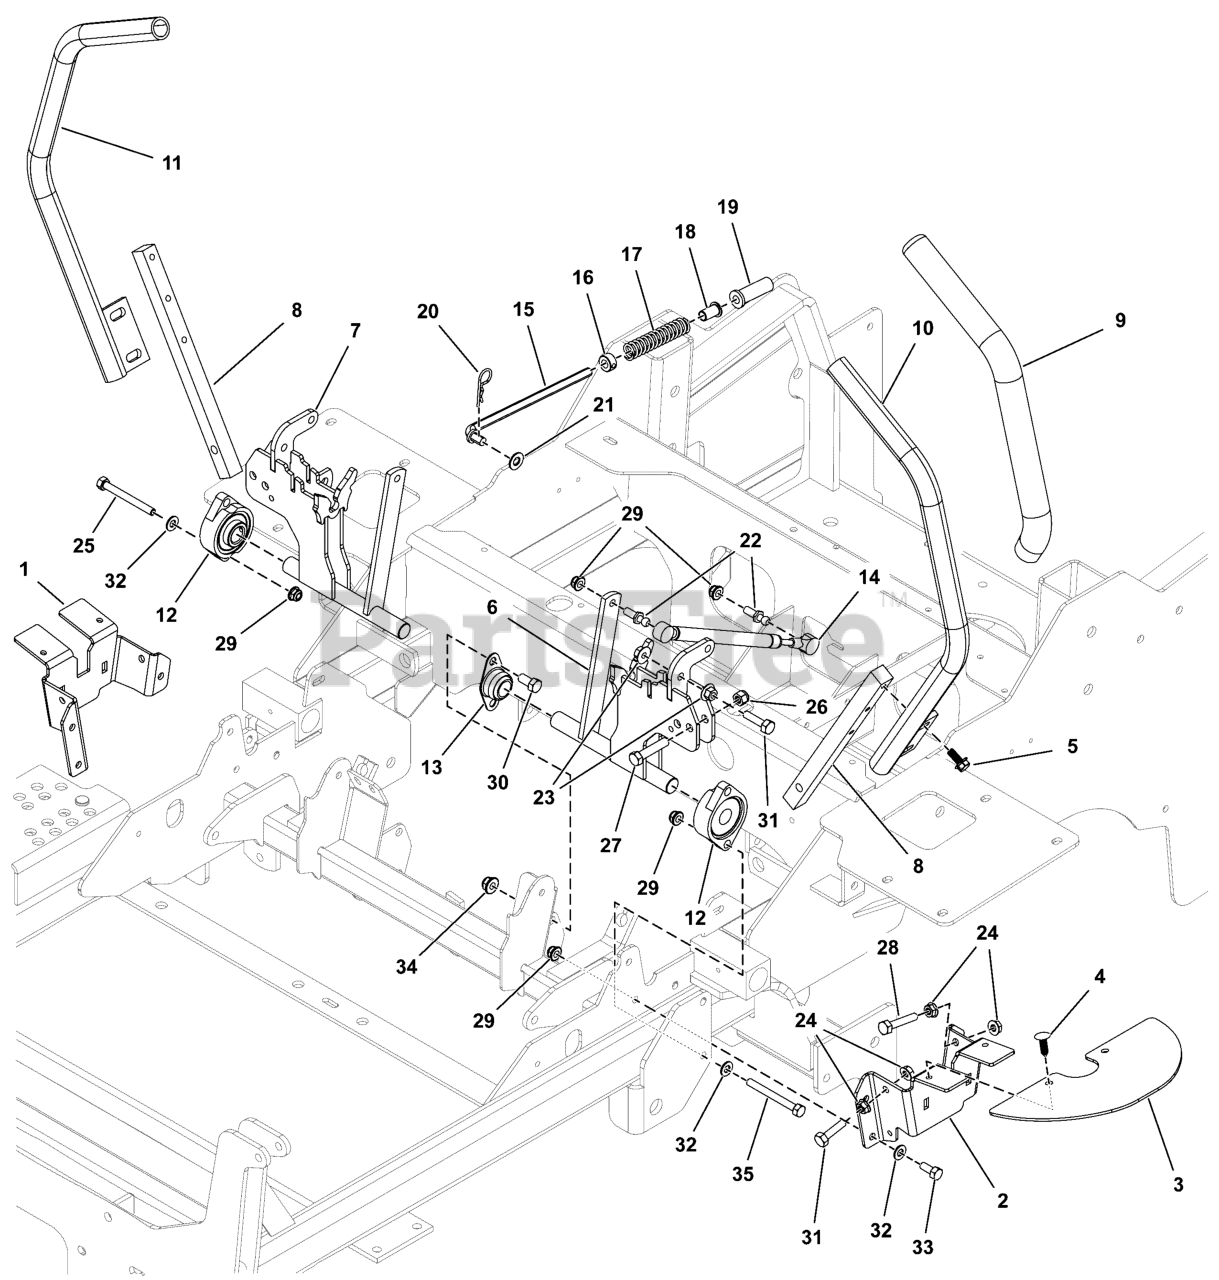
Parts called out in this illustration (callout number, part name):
1	PLATE, Neutral Lock, RH - BLK
2	PLATE, NEUTRAL LOCK, LH - BLK
3	GUARD, RUBBER MOTION CONTROLS
4	PUSH RIVET (TREE TYPE), BLACK
5	SCREW, 5/16-18x0.750, GR5, WHIZ-LOCK, ZC
6	WELD, CONTROL SHAFT, LOCKOUT, LH - BLK
7	WELD, CONTROL SHAFT, LOCKOUT, RH - BLK
8	MOUNT, CONTROL ARM - BLK
9	GRIP, FOAM, 1" ID, 16" LONG
10	WELD, HANDLE MOTION CNTRL, 16.5, 1.0, LH - BLK
11	WELD, HANDLE MOTION CNTRL, 16.5, 1.0, RH - BLK
12	BEARING, FLANGE
13	BEARING, BRONZE FLANGE, 3/4"
14	DAMPENER, CONTROL,#(P6709/P3610)
15	ROD, NEUTRAL RETURN, CZ
16	COLLAR, 3/8" Set
17	SPRING, REVERSE RETURN
18	BUSHING, FLANGE 3/8ID X 7/8 LONG
19	FLANGED BUSHING, 3/8IDX.63ODX.8125FL
20	3/32 X 1-5/8 HAIR PIN CLIP
21	WASHER, 3/8 SAE
22	10MM BALL STUD, 5/16-18 X 3/4 THDS
23	NUT, 5/16-18 HEX SERRATED FLANGE (LARGE)
24	NUT, 5/16-18 HEX SERRATED FLANGE (SMALL)
25	BOLT, 5/16-18 X 3" GD5 YZ
26	NUT, 3/8-16 HEX NYLON LOCK
27	BOLT, 3/8-16 X 1-3/4" GD5 CZ
28	BOLT, 5/16-18 X 1-3/4 TFL, GD5 YZ
29	NUT, 5/16-18 HEX NYLOCK FLANGE NUT
30	BOLT, 3/8-16 X 3/4" GD5 CZ
31	BOLT, 5/16-18 X 1-1/4 GD5 TFL, CZ
32	WASHER, 5/16" SAE
33	BOLT, 5/16-18 X 3/4 GD5
34	NUT, 3/8 - 16 HEX NYLOCK FLANGE
35	BOLT, 5/16-18 X 3-1/4 GD5
